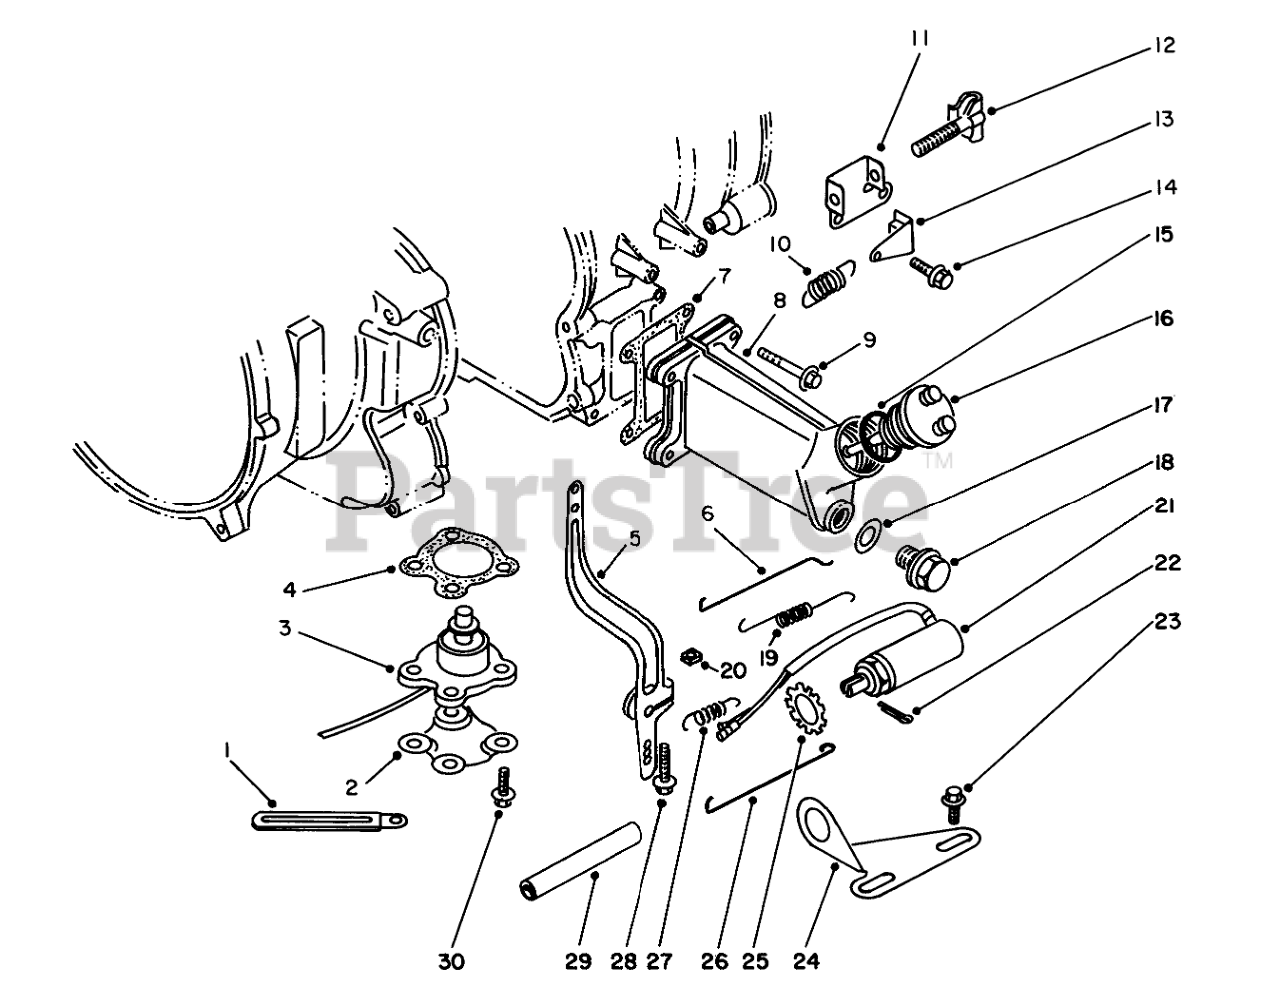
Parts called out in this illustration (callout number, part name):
1	Clamp
2	Plate
3	Oil Level Sensor
4	GASKET
5	Lever-Throttle Control
7	Gasket
8	Case-Oil Filler
10	Spring
11	Bracket
12	Bolt-Hook
15	O-RING
16	Oil Gauge
17	GASKET
19	Spring
21	Solenoid
24	Bracket
25	Lockwasher
27	SPRING
